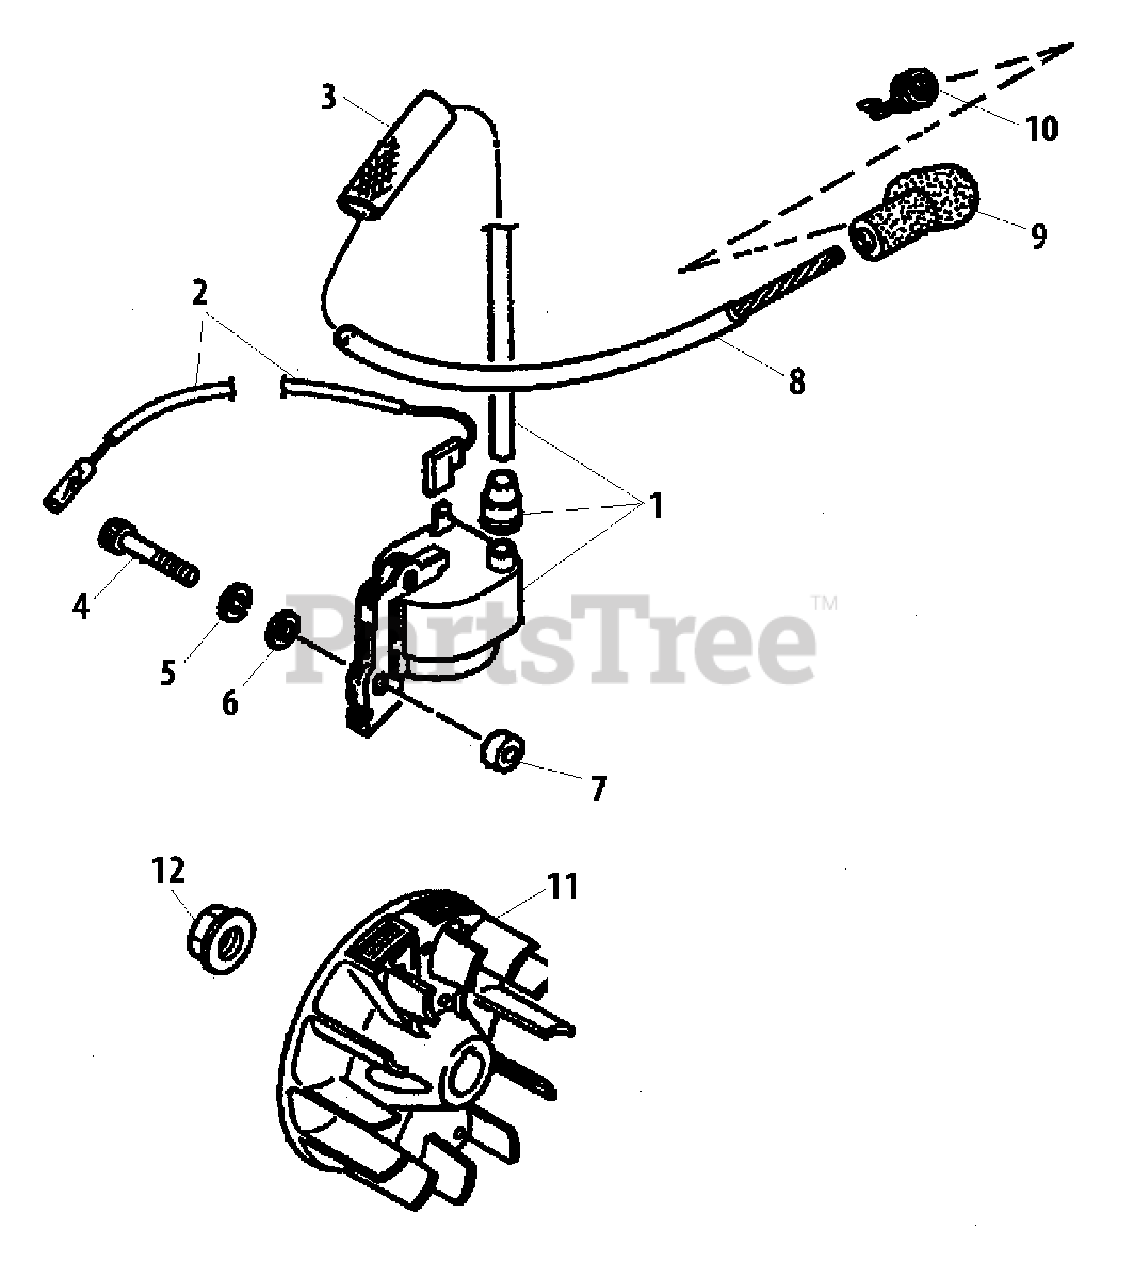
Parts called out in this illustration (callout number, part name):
1	IGNITION COIL ASSY
2	WIRE
3	TUBE
4	SCREW - 4X26
5	LOCKWASHER - 4
6	WASHER - 4
7	INSULATOR
8	TUBE
9	CAP, SPARK PLUG
10	TERMINAL, SPARK PLUG CAP
11	FLYWHEEL
12	NUT - 8
